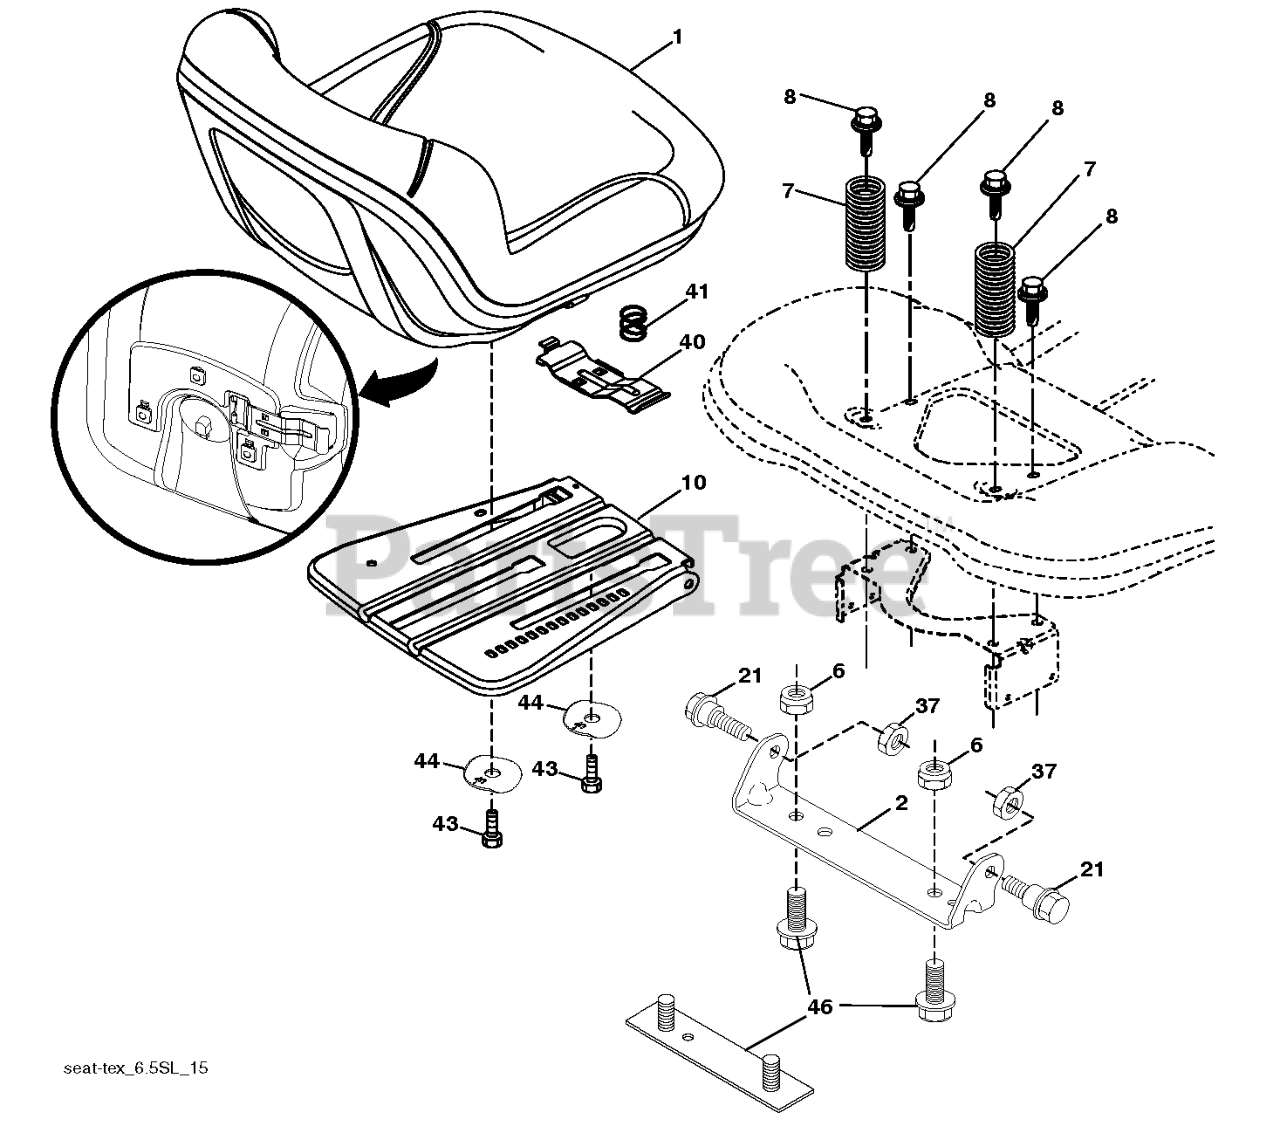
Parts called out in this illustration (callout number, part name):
1	SEAT.TH130.GREY.HUSQ.TEX
2	BRKT.PIVOT.FENDER
6	NUT
7	SPRING.COMPRESS.SEAT.TAPERED
8	BOLT.5/16-18UNCX3/4 W/SEMS.BLK
10	PLATE SEAT; SLIDE; 3PT BLACK;
21	BOLT.5/16-18X5/8.SHOULDER
41	SPRING.LATCH.SEAT.TEX
44	WASHER.WINGED.3/8ID.1.5OD
46	BOLT.3/8-16X1;1.25OD.WSHR.SEMS
46	STRAP
